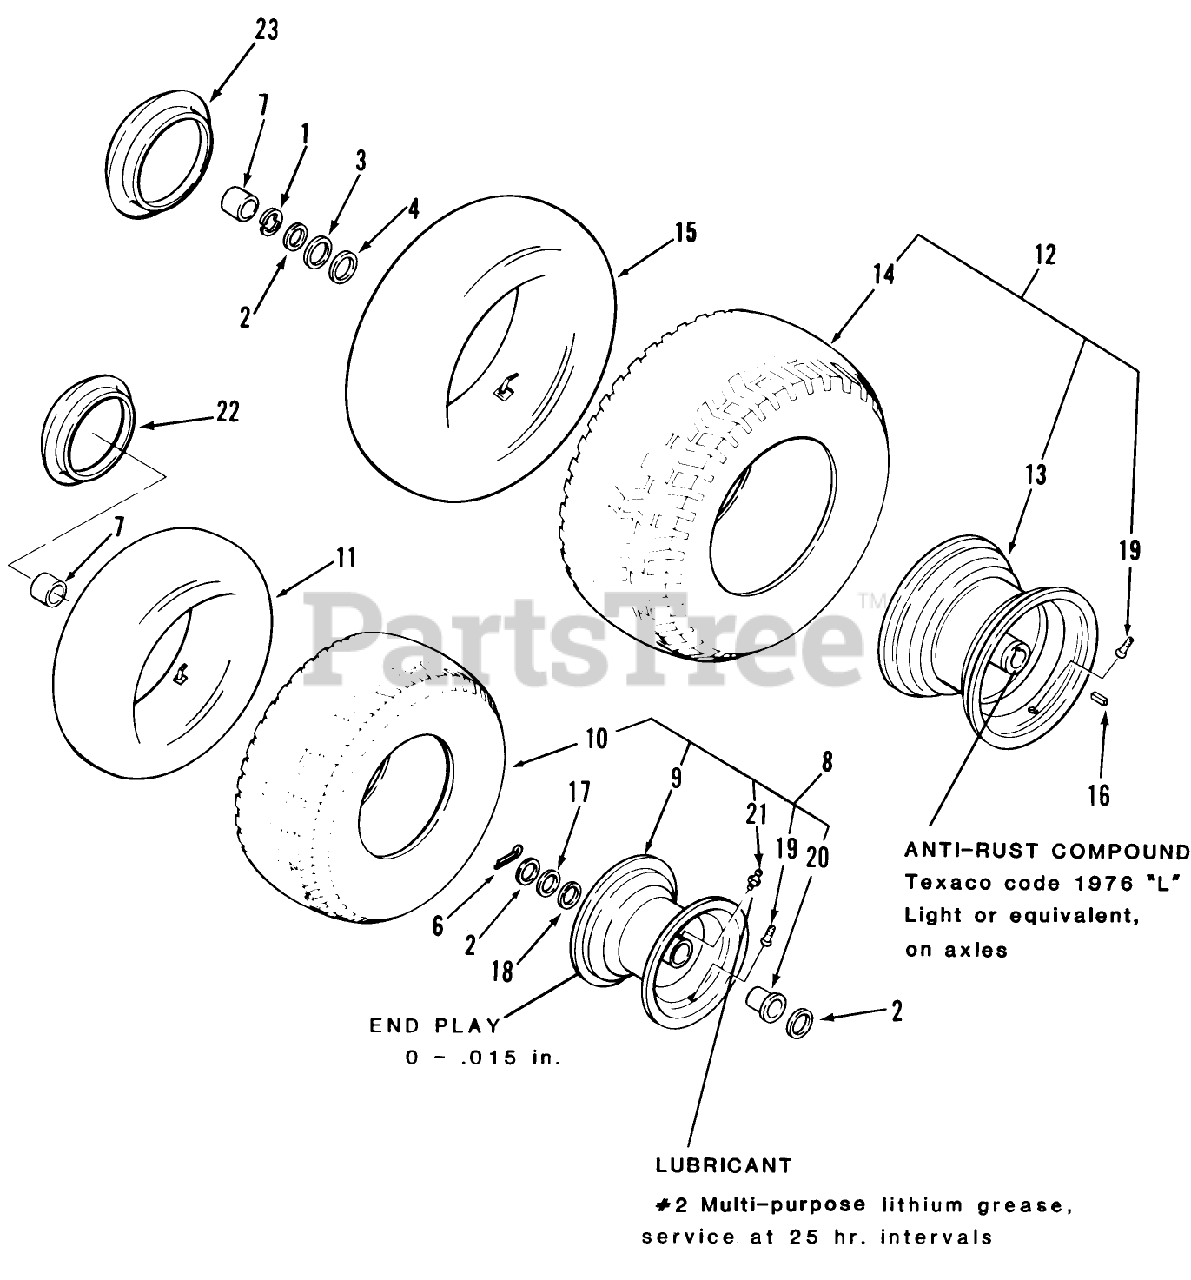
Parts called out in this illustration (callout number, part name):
2	WASHER-FLAT
3	WASHER-SHIM
4	WASHER
6	COTTER PIN-4
9	ASSY WHEEL
16	SQ KEY
17	WASHER
18	WASHER-SHIM
19	VALVE
20	BUSHING-FLANGED
21	ZERK-GREASE
